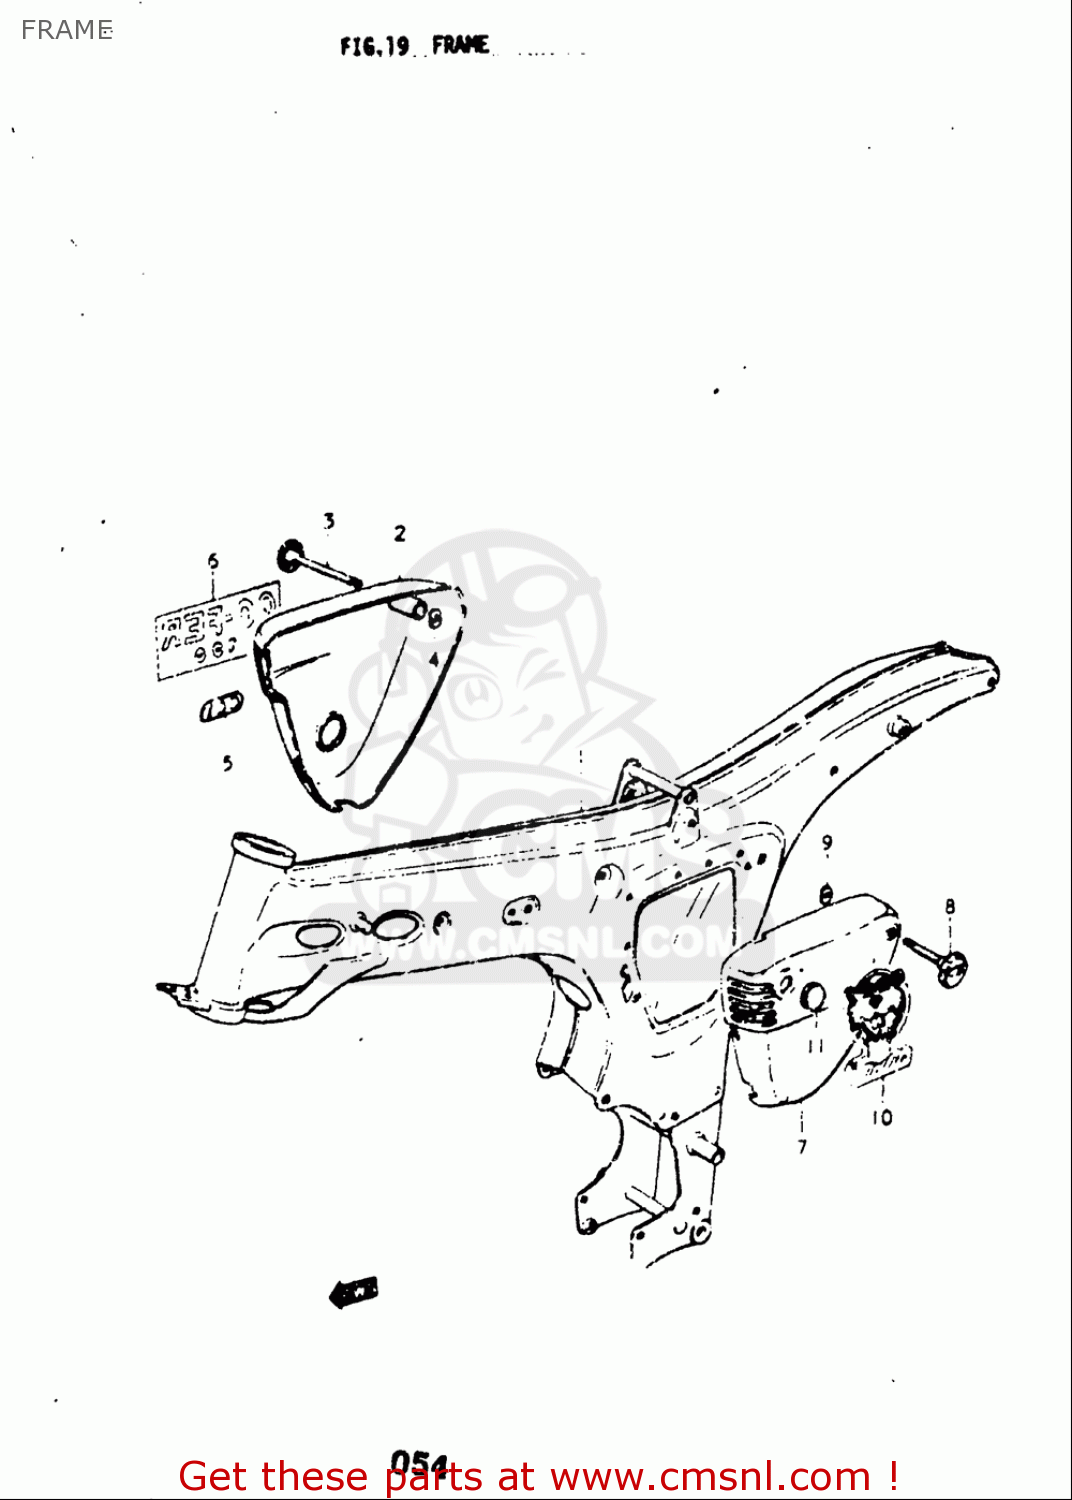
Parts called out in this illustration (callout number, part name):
3	KNOB,FRAME COVER,R
4	NUT
5	EMBLEM,CCIS
7	COVER,FRAME,LEFT
8	KNOB,FRAME COVER,L
9	NUT
11	CAP,FRAME COVER,LEFT
